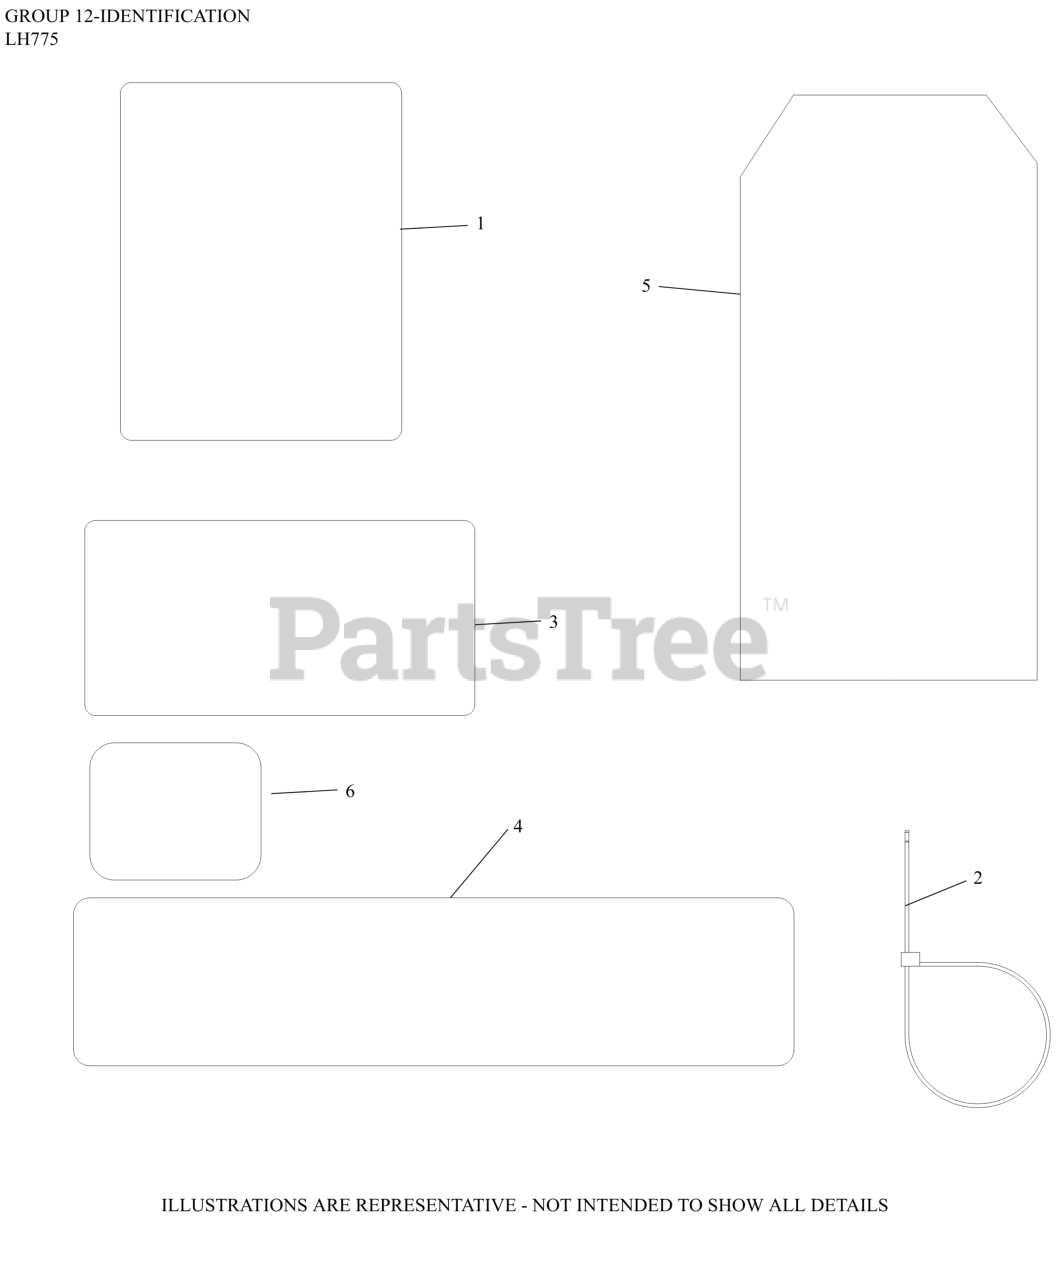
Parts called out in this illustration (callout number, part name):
1	LABEL, CLEAR LAMINATION
3	DECAL, ROTATING FAN WARNING-DISC.
5	TAG, HANG (NO COOLANT)
6	DECAL, WARNING
